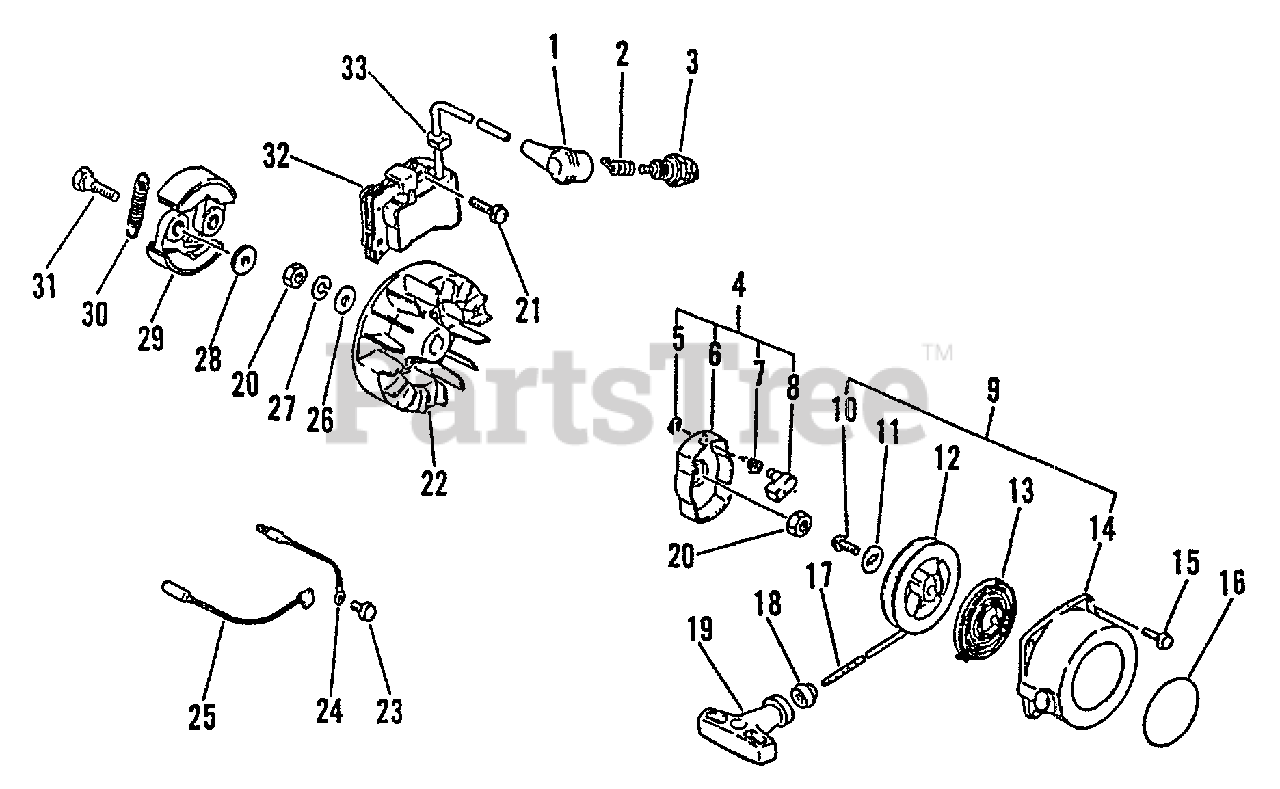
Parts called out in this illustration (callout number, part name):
1	CAP, SPARK PLUG
2	TERMINAL, SPARK PLUG CAP
3	SPARK PLUG -- BPM-7A
4	STARTER PAWL ASSY
5	RING, RETAINING - 4
6	CATCHER, PAWL
7	SPRING, RETURN
8	PAWL, STARTER
9	STARTER ASSY - GRAY
11	WASHER
12	REEL, ROPE
13	SPRING, REWIND
14	CASE, STARTER
15	SCREW - 4X14
16	LABEL - LESCO
17	ROPE, STARTER - 3.5X850
18	GUIDE, ROPE
19	GRIP, STARTER
21	SCREW - 5X20
22	FLYWHEEL
23	SCREW - 5X10
24	LEAD - GROUND
25	LEAD - GROUND
26	WASHER - 8
27	LOCKWASHER - 8
28	WASHER - 6
29	SHOE, CLUTCH
30	SPRING, CLUTCH
31	BOLT, CLUTCH
32	COIL, IGNITION
